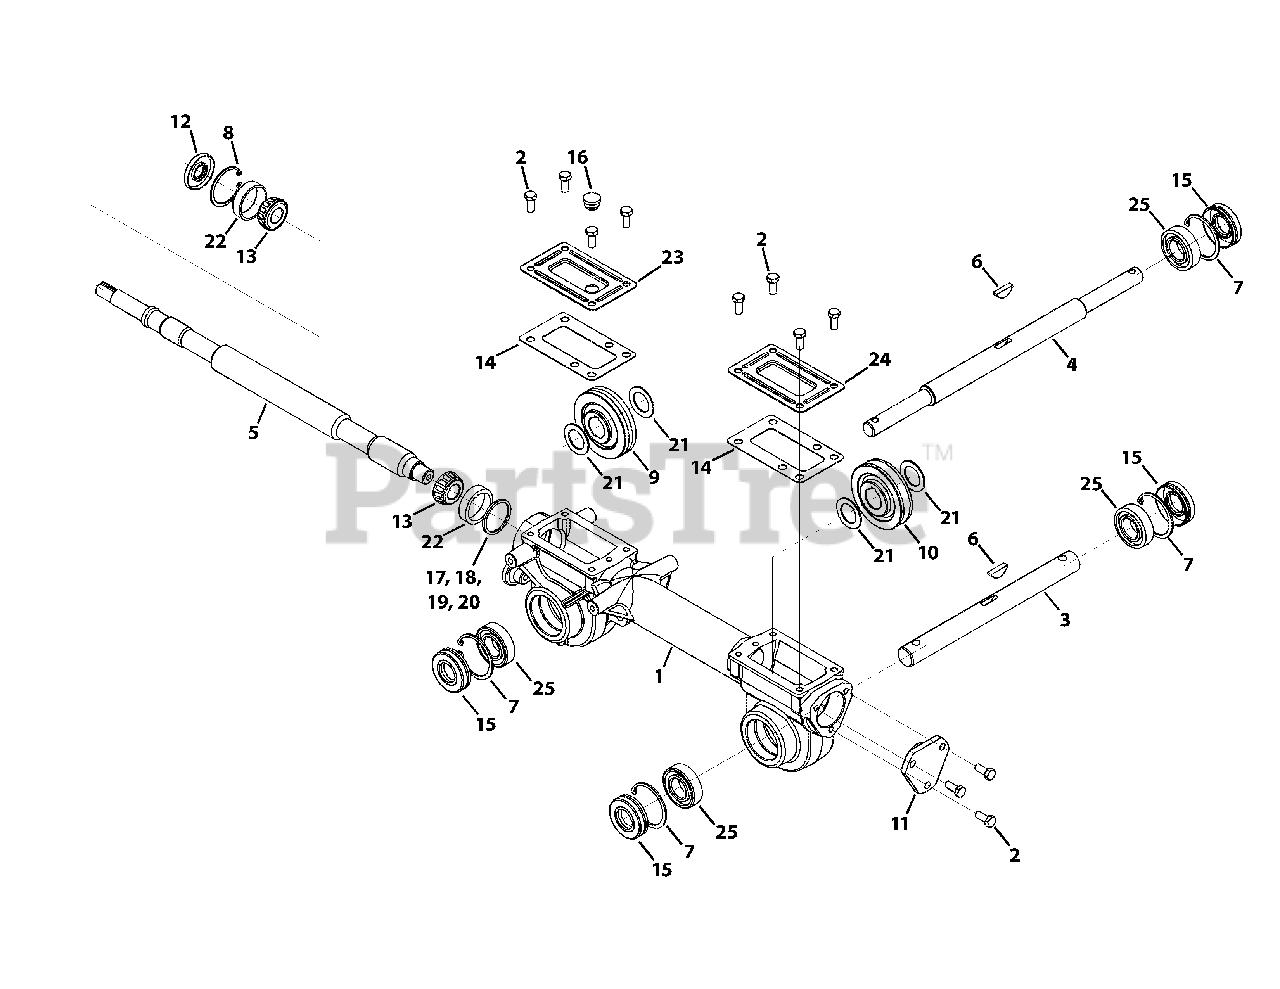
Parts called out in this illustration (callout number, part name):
1	Transmission Housing
2	Hex Head Screw, 5/16-18 x .75
3	Tiller Shaft
4	Wheel Shaft
5	CRT Drive Shaft
6	Key, .25 x 1.062
7	Retainer Ring
8	Retainer Ring
9	RH Gear Worm, 61T
10	LH Gear Worm, 30T
11	Bearing Cover
12	Oil Seal, .750 SHF x 1.783 BORE
13	Cone Bearing
14	Gear Housing Gasket
15	Oil Seal, 1.00 SHF x 2.00 BORE
16	Rubber Oil Plug
17	Washer, Flat, 1.50 x 1.75 x .062
18	Washer, Flat, 1.50 x 1.75 x .005
19	Washer, Flat, 1.50 x 1.75 x .03
20	Washer, Flat, 1.50 x 1.75 x .010
21	Washer, Flat, 1.010 x 1.56 x .060
22	Cup Bearing
23	Tiller Transmission Cover
24	Tiller Transmission Cover
25	Ball Bearing, 1 x 52 x 15 x 6205-1
